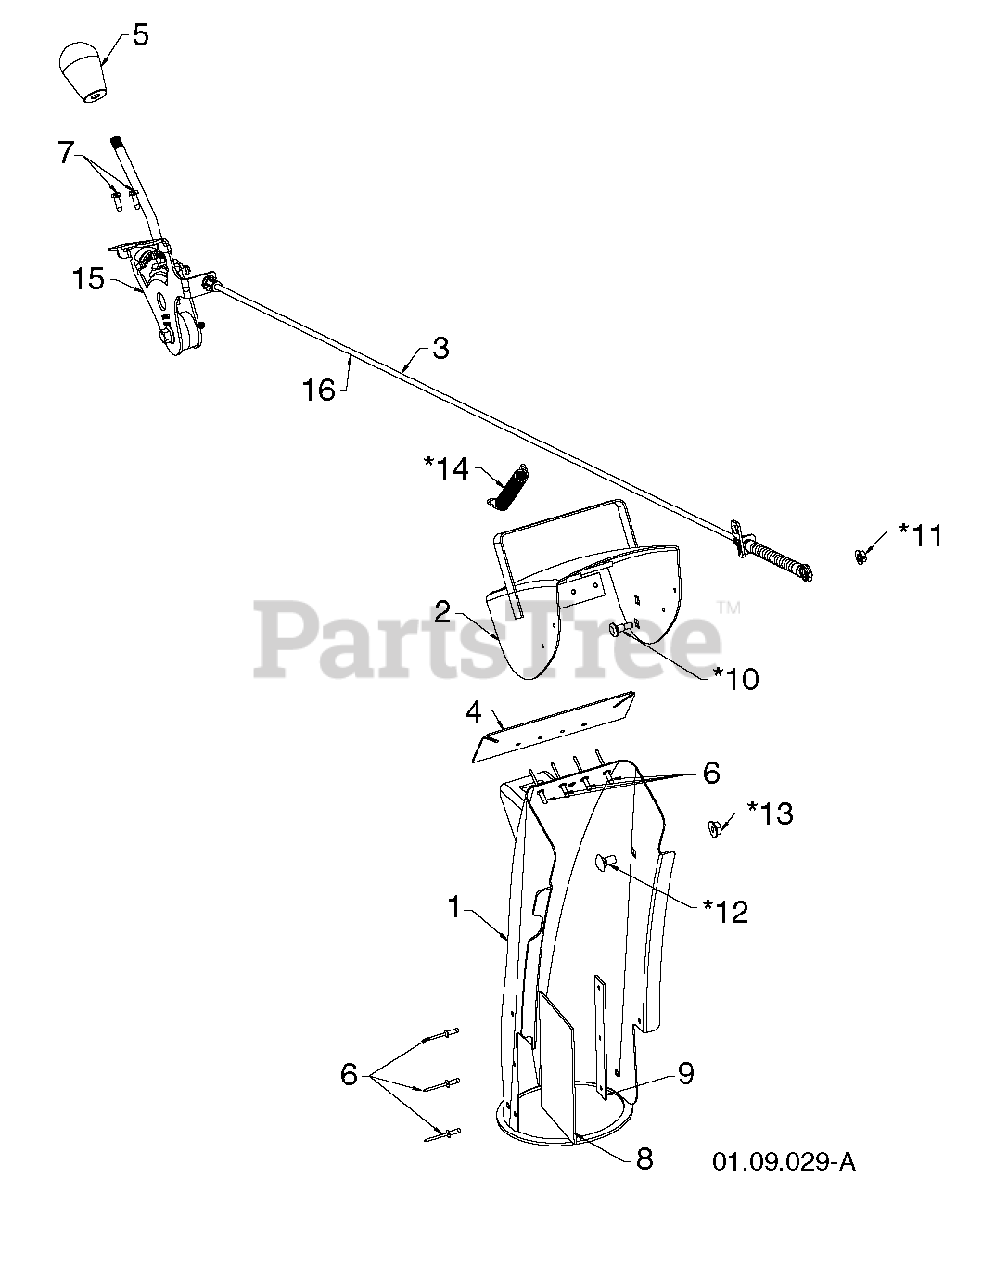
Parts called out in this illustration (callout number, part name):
1	RP_CHUTE.WELDMENT.SNOW.ORANGE
2	DEFLECTOR.WELDMENT.PNT.ORANGE
3	RP.CONTROL.ASM.DEFLECTOR.SNOW
4	SEAL.DEFLECTOR
5	KNOB.OVERMOLD.DS.HUSQVARNA/BLK
6	RIVET BLIND
7	SCREW #10-24 X 5/8
8	SHIELD.SNOW.CHUTE
9	STRAP.SHEILD.RETAINER
10	BOLT, SHOULDER
11	NUT.HEX.FLANGE.1/4
12	BOLT
13	NUT.LOCK.5/16-18
14	SPRING.DEFLECTOR.REM.CHUTE
15	RP CNTRL.HEAD.ASSEM.DEFLECTOR
16	RB SERVICE.CHUTE.DEF.CBL.BLK
